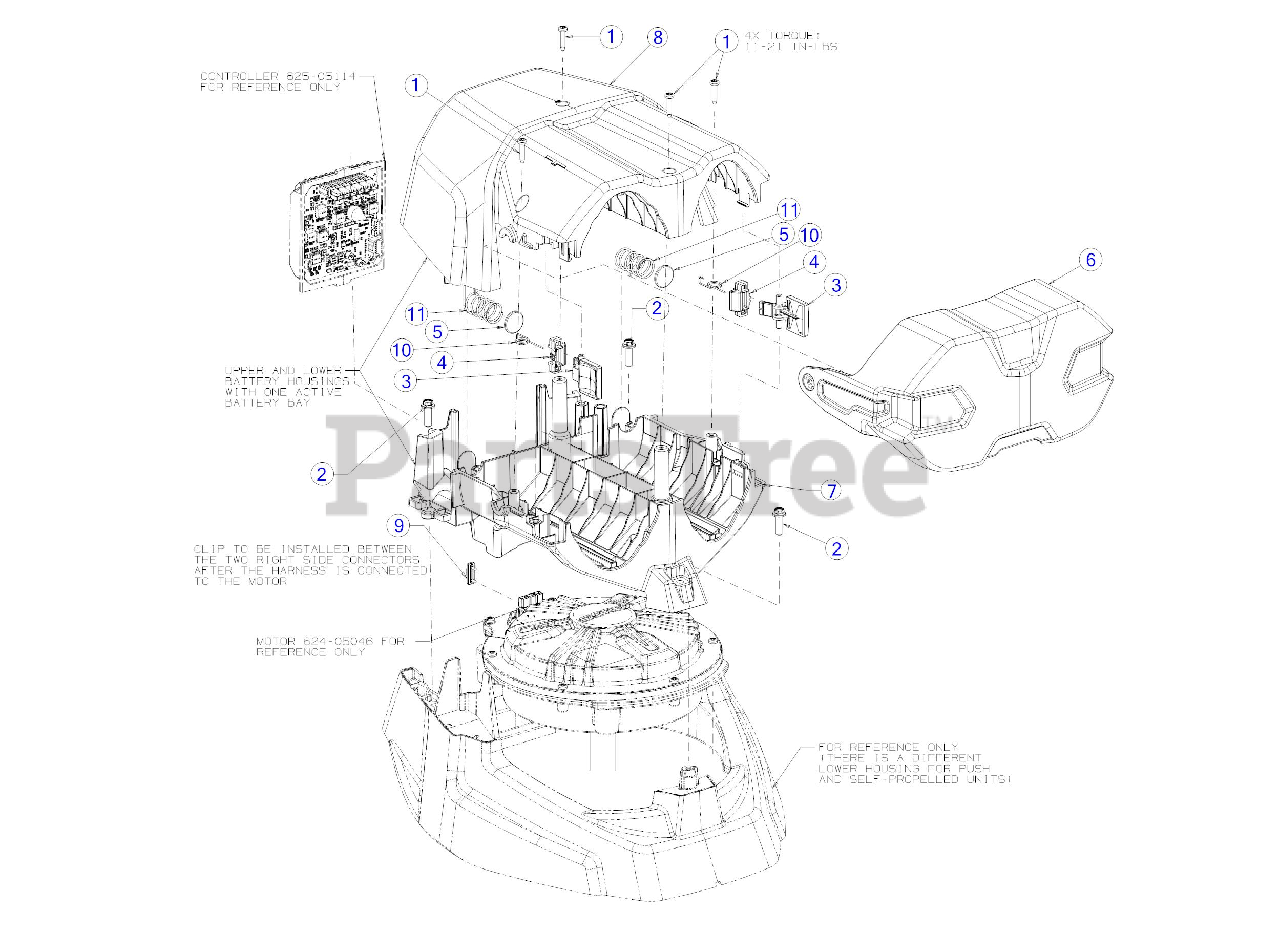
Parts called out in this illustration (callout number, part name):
1	SCREW 7-18X.75:T20
2	SCREW 1/4 x .750
3	BATTERY LATCH
4	BATTERY RELEASE LATCH
5	BATTERY RELEASE SPRING CAP
6	BATTERY HOUSING LID
7	MIDDLE BATTERY HOUSING
8	SINGLE BATTERY UPPER HOUSING
9	RETAINING CLIP
10	TRIGGER SPRING
11	BATTERY RELEASE SPRING
